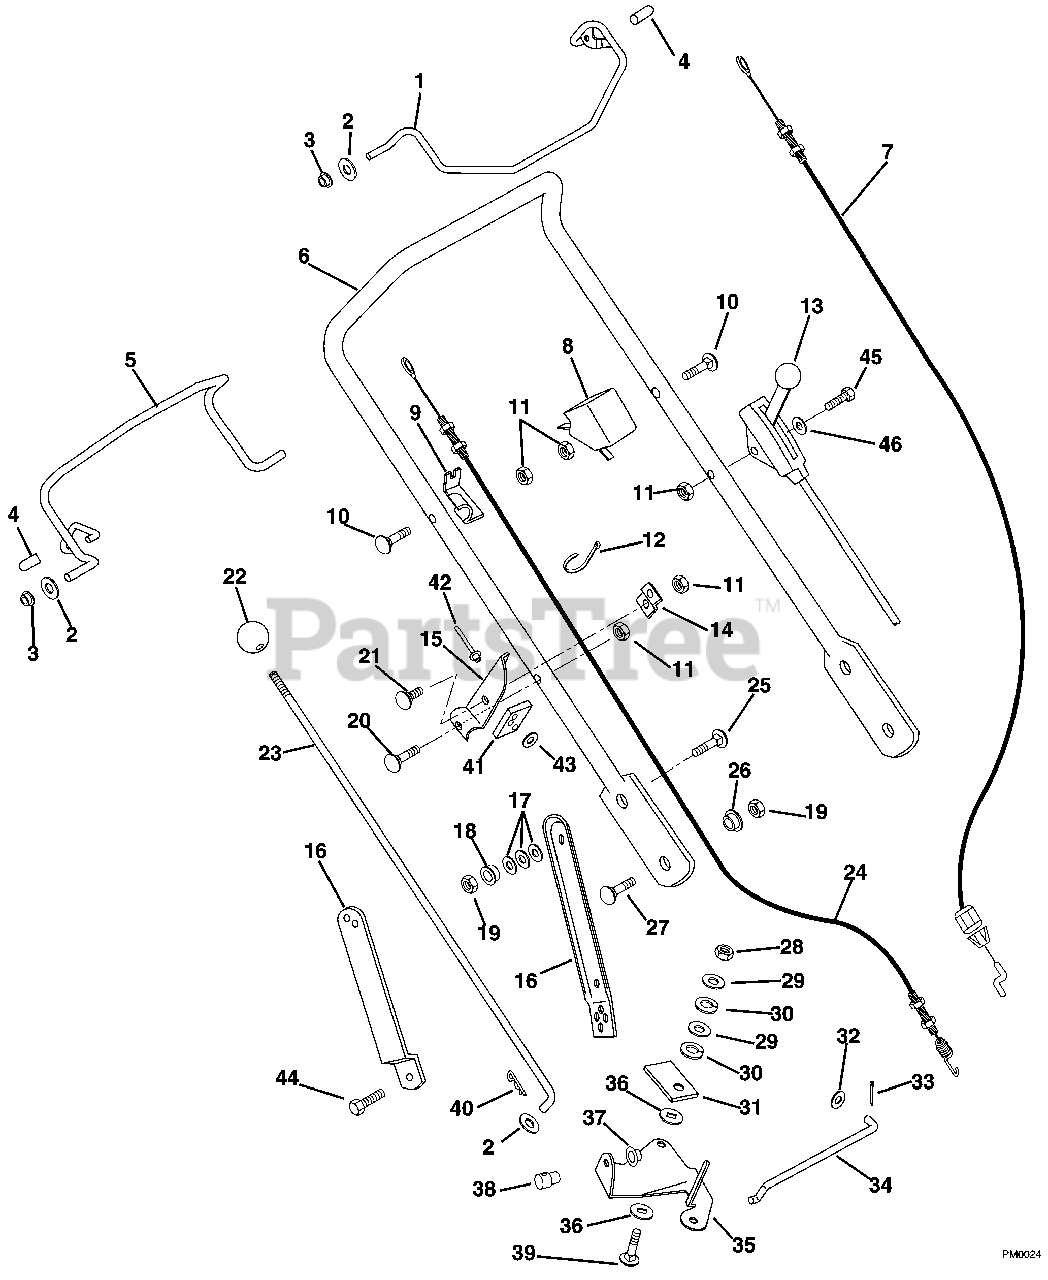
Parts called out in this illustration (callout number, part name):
1	Engine Bail Weldment
2	Washer-Flat-Steel .325 x .688 x .065
3	Bushing-Flange .325 x .688 x .560
4	Cap, Vinyl .25 I.D.
5	Traction Bail
6	Handlebar, Self Propelled
7	Engine Control Cable (580 RS, 580 RSE, 580 RSW)
8	Switch-Cable Anchor (580 RSE)
9	Cable Anchor-Right Hand
10	Bolt-Round Head Square Neck .25-20 x 1.25
11	Nut-Locking-Center .25-20
13	Throttle Cable (600 C)
14	Brace-Speed Control
15	Bracket-Speed Control
16	Link-Handlebar Adjuster Left Hand (580 RS, 580 RSE, 580 RSW)
17	Washer-Bellville Spring (580 RS, 580 RSE, 580 RSW)
18	Bushing-Flange .325 x .500 x .513 x .875 (580 RS, 580 RSE, 580 RSW)
19	Nut-Locking-Center .31-18
20	Bolt-Round Head Square Neck .25-20 x 1.38
21	Bolt-Round Head Square Neck .25-20 x .50 Grade 5
23	Rod-Speed Control
24	Traction Cable
25	Bolt-Round Head Square Neck .31-18 x 1.00 Grade 5
26	Shoulder Spacer
27	Bolt-Round Head Square Neck .31-18 x .75 Grade 5 (580 RS, 580 RSE, 580 RSW)
28	Nut-Locking-Center .38-16
29	Washer-Flat-Steel .406 x .812 x .065
30	Washer-Lock .375 x .115 Heavy
31	Pressure Flange
32	Washer-Flat-Steel .281 x .620 x .065
33	Pin-Cotter .06 x .50
34	Shift Link
35	Bell Crank-Speed Control
36	Friction Washer
37	Cap, Rod .375
39	Bolt-Round Head Square Neck .38-16 x 1.50
40	Pin-Hair-Internal .08 x .18 x 1.18
41	Support Pad
42	Rivet .187 x .575
43	Washer-Flat Steel .219 x .50 x .049
44	Bolt-Hex .31-18 x .75 Grade 5 (600 C)
45	Bolt-Hex .25-20 x 1.75 Grade 5 (600 C)
46	Washer-Flat-Steel .250 x .562 x .049 (600 C)
